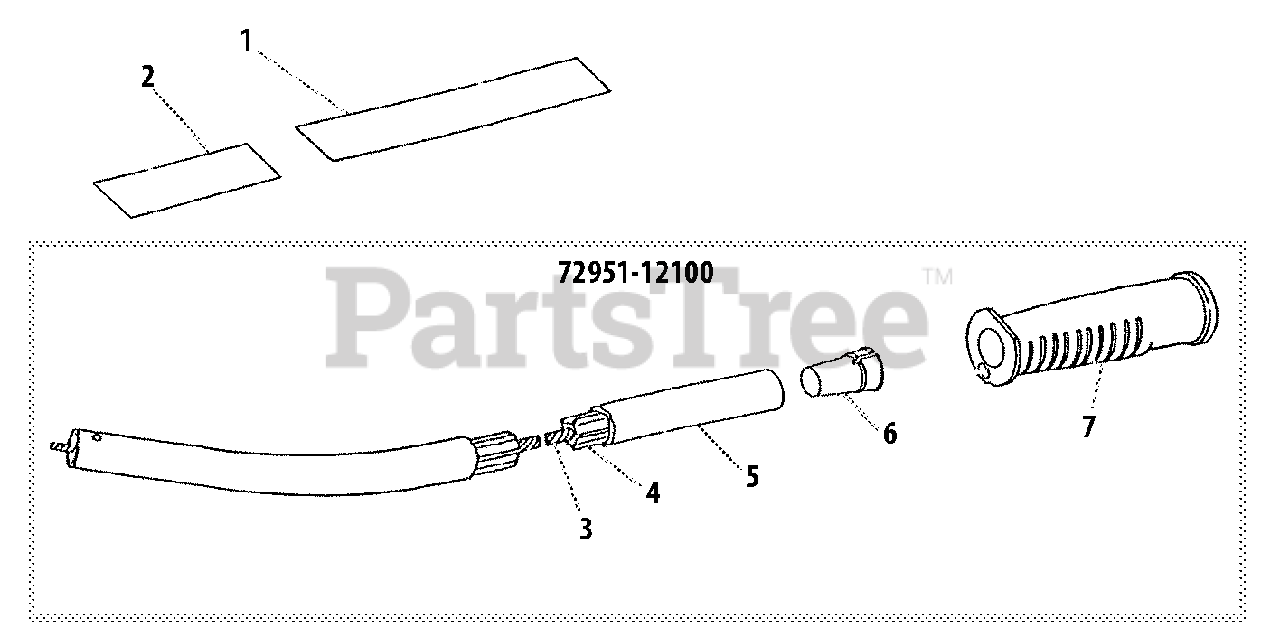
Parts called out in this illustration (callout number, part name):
1	LABEL - MODEL
2	LABEL, CAUTION
3	DRIVESHAFT - FLEXIBLE
4	LINER - FLEXIBLE
5	MAIN PIPE ASSY
6	GUIDE, SHAFT
7	GRIP, REAR
72951-12100	MAIN PIPE ASSY
